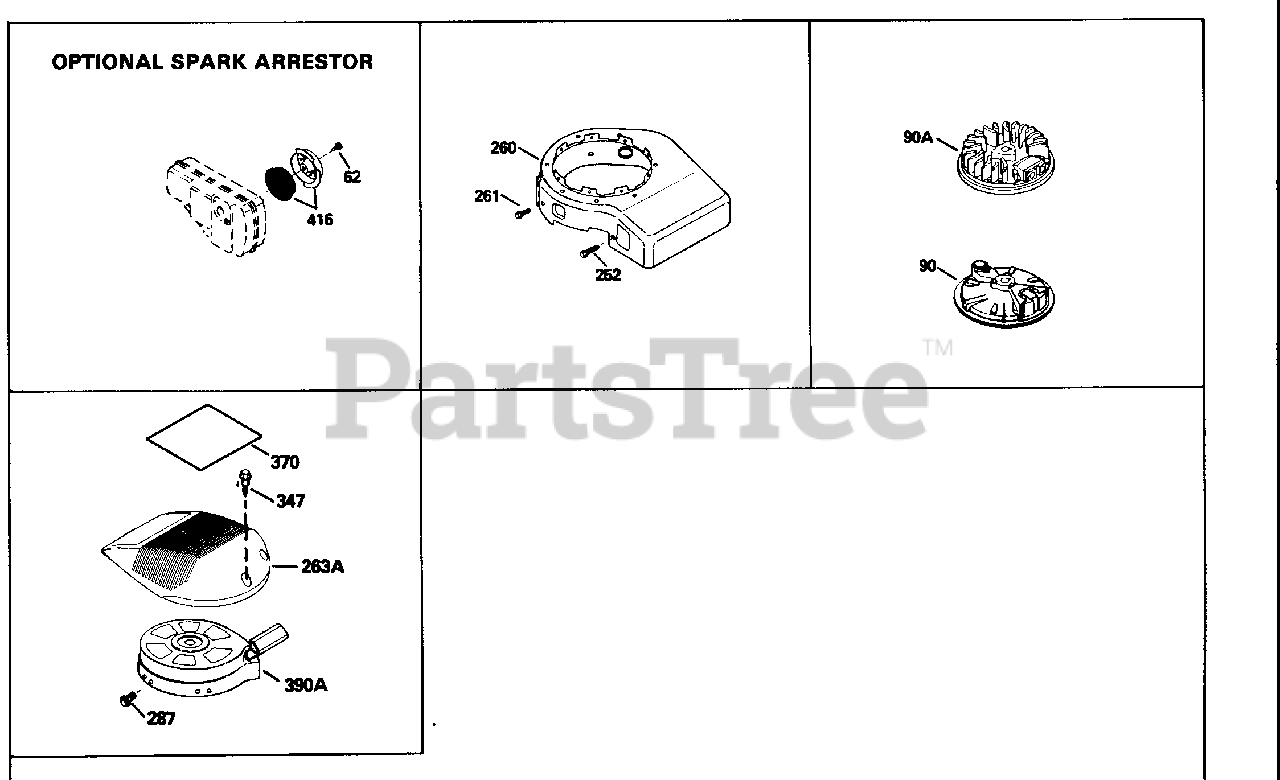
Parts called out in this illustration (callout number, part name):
252	Screw, 1/4-20 x 11/16"
261	Screw, 1/4-20 x 1/2"
287	Screw, 8-32 x 21/64"
370	Instruction Decal
999	Summer Maintenance Kit (incl. Oil, Sp ark Plug, Air Cleaner, & Ultra Fresh)
